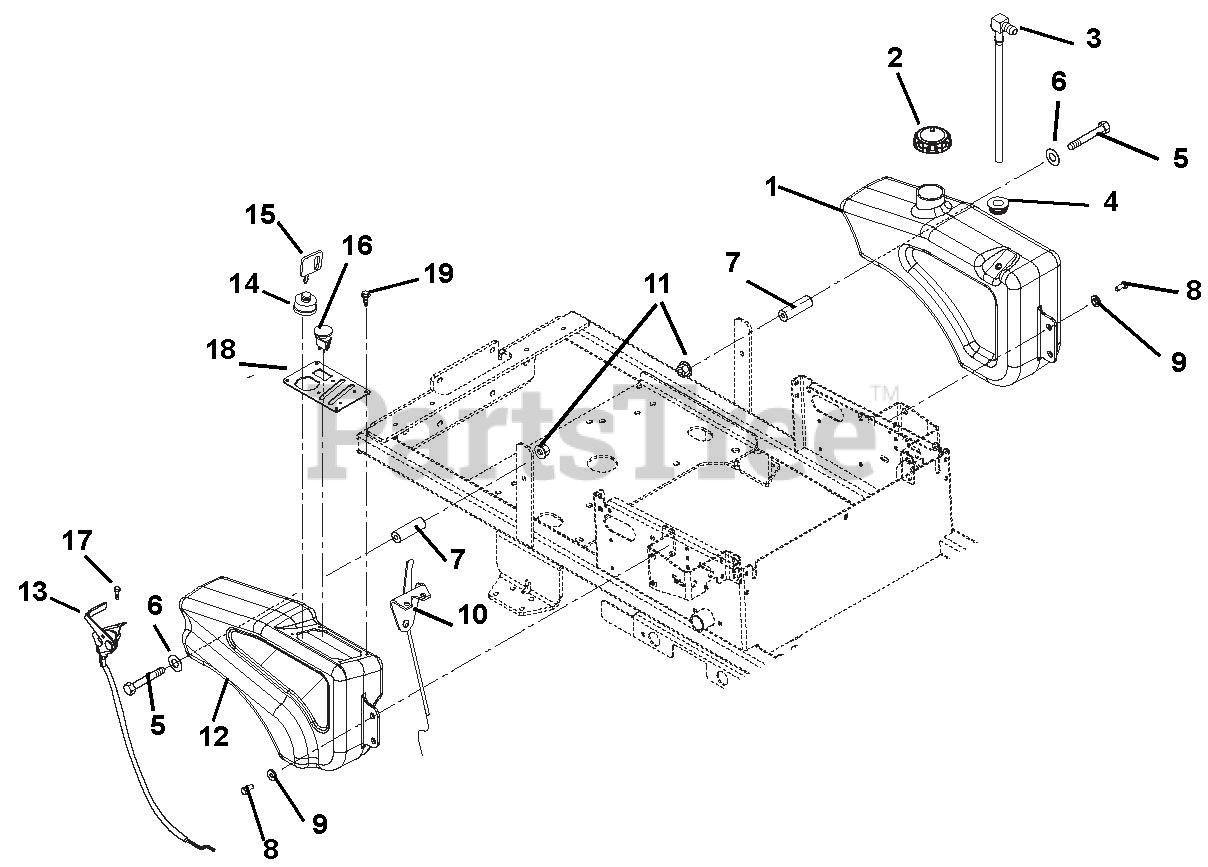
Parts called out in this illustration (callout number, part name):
1	GAS TANK, ZOOM
2	FUEL CAP
3	FITTING, TANK
4	BSHG-FLG .375 X 1.062 X .625 R
5	@BLT-HEX .31-18X3.50 GR5 YWZC
6	@WSHR-FL-STL.38X.875X.083 YWZC
7	SPCR, FLG .32X.49X.15X2.64
8	@BLT-HEX .31-18X.75 GR5 YWZC
9	BSHG, FLG .325X.499X.26X.88
10	THROTTLE/CHOKE CABLE
11	@NUT-LK-NYL-FLG .31-18 YWZC
12	FENDER, ZOOM
13	CABLE, THROTTLE
14	KEY SWITCH
15	KEY -W/CAP
16	SWITCH, CLUTCH
17	@SCR-TAP 10-24X.50 HWH TR YWZC
18	CONTROL PANEL
19	RIVET, PLASTIC .195 DIA.
